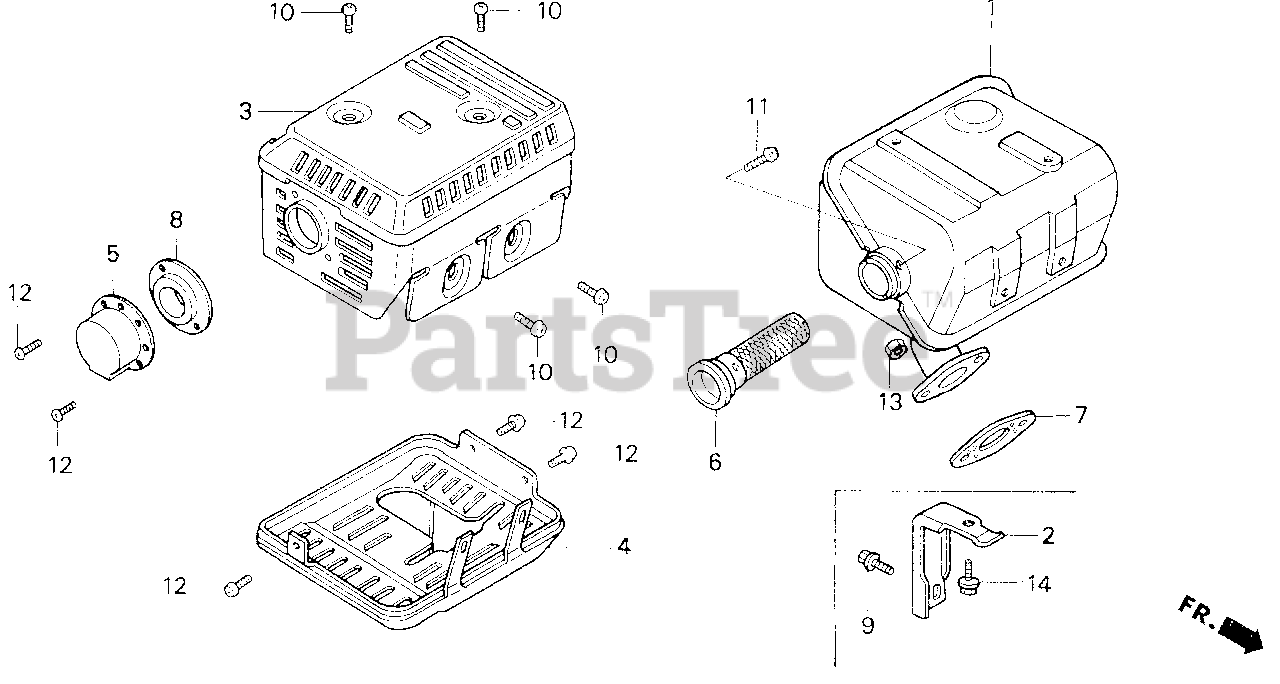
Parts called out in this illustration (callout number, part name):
1	MUFFLER
3	PROTECTOR, MUFFLER
5	DEFLECTOR
6	ARRESTER, SPARK
7	GASKET, MUFFLER
8	GUIDE, MUFFLER
10	SCREW, TAPPING (5X8)
11	SCREW, TAPPING (4X6)
12	SCREW, TAPPING (4X8)
12	SCREW, TAPPING (4X6)
13	NUT, HEX. (8MM)
